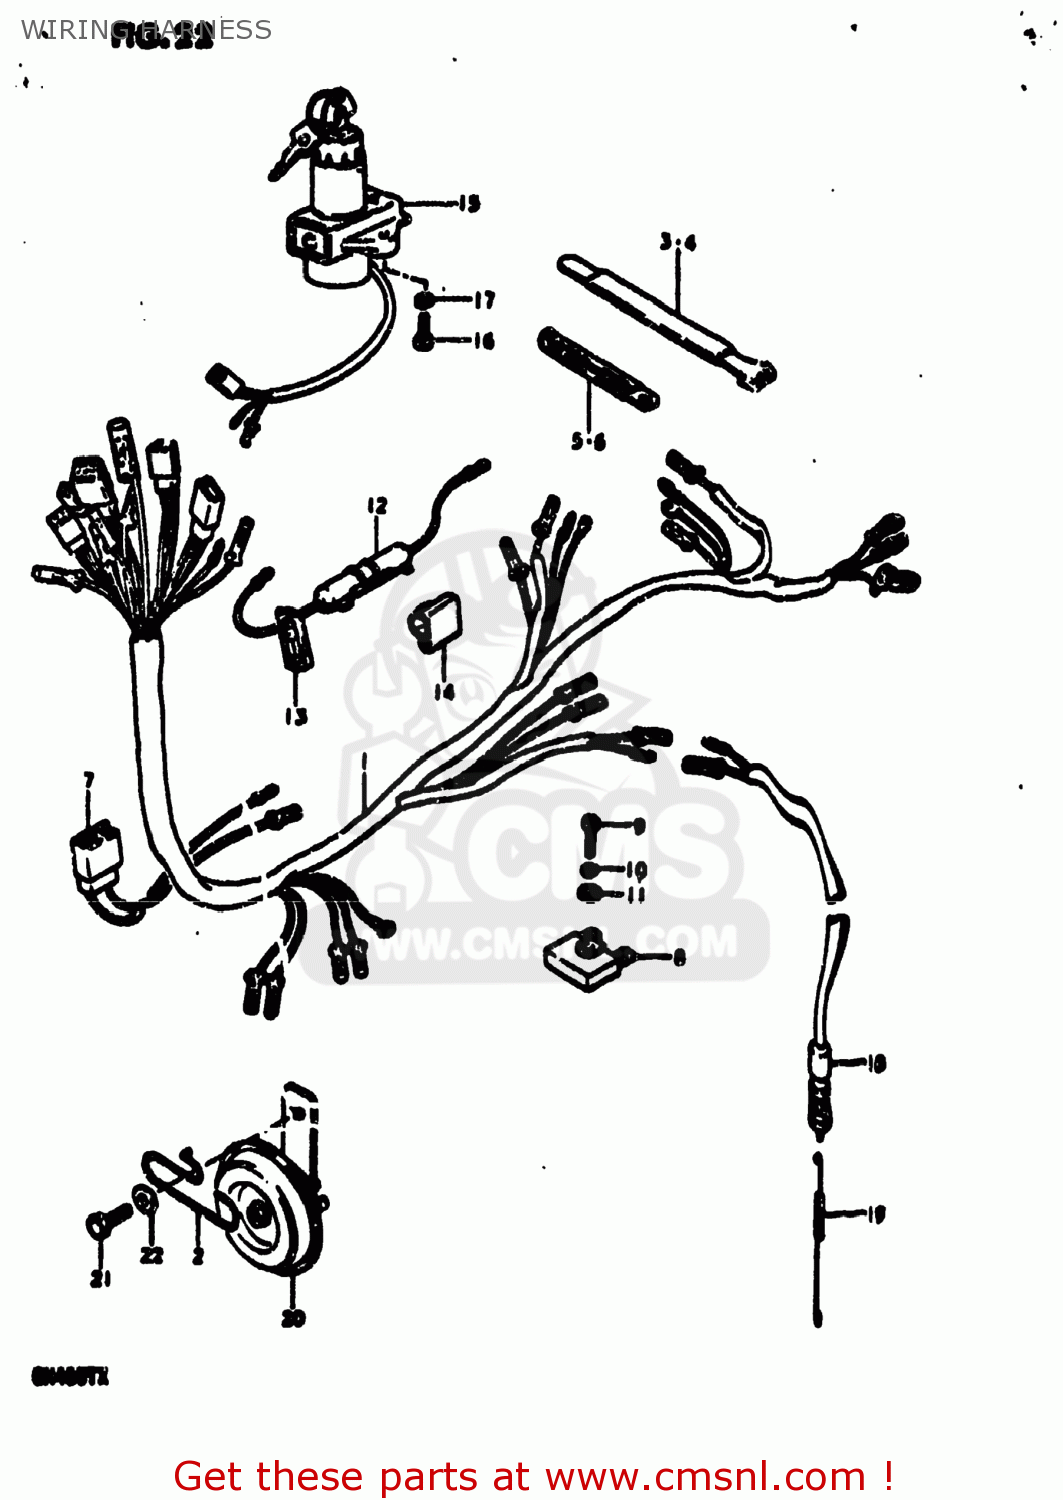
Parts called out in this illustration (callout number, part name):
1	HARNESS,WIRING
2	CLAMP,WIRING HARNESS
3	CLAMP
4	CLAMP
5	CLAMP
6	CLAMP
7	WIRE,DC LIGHTING
8	RECTIFIER ASSEMBLY
9	SCREW 5X20
10	LOCK WASHER
11	WASHER
12	BOX ASSEMBLY,FUSE
13	FUSE(15A)
14	HOLDER,FUSE CASE
15	LOCK ASSEMBLY,STEERING
16	BOLT
17	LOCK WASHER
18	SWITCH ASSEMBLY,STOP LAMP
19	SPRING
20	HORN ASSEMBLY
21	BOLT
22	WASHER
